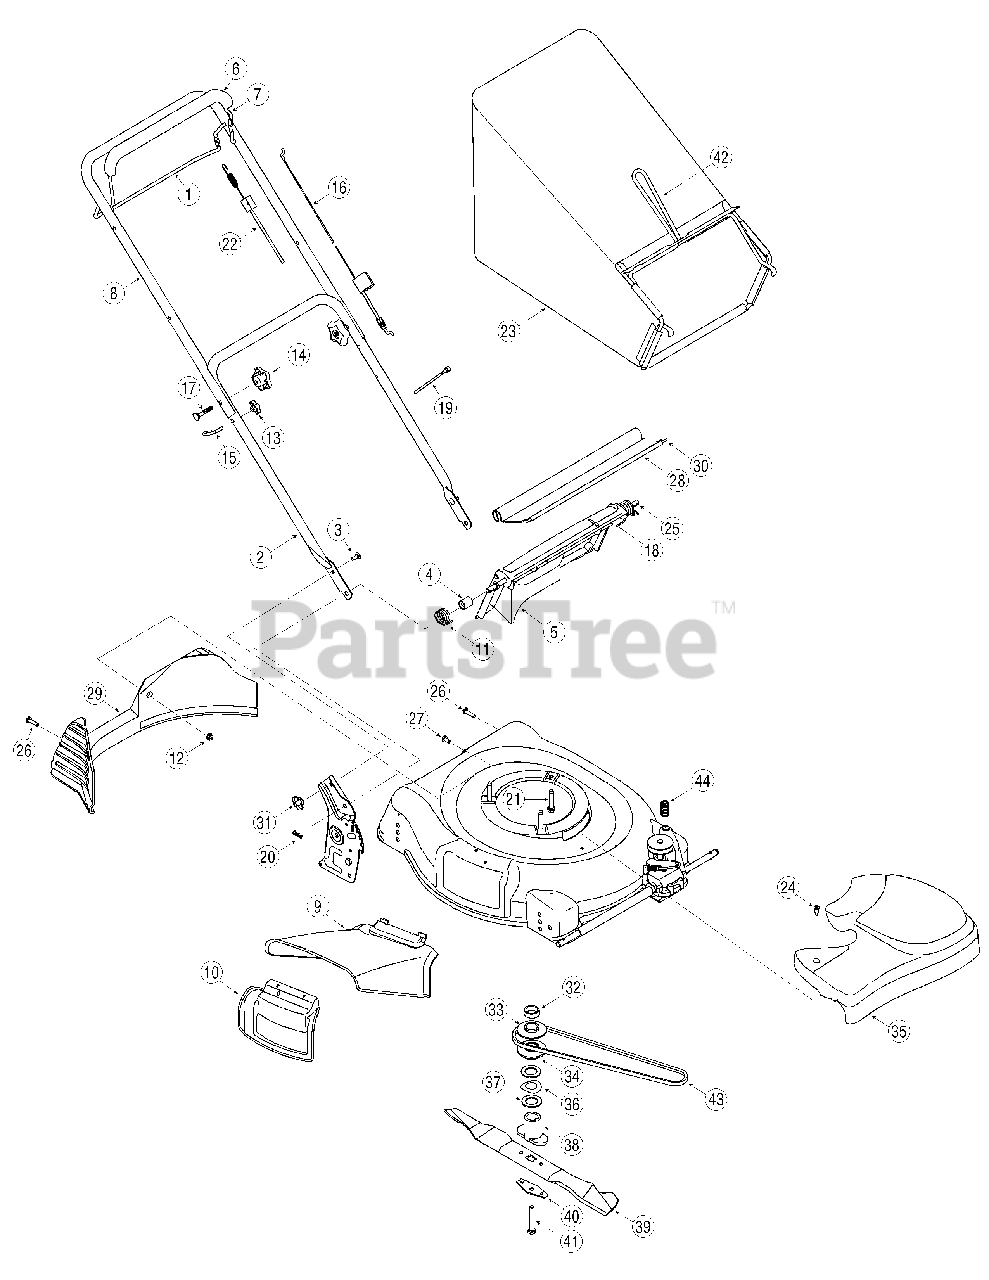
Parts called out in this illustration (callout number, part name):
1	Drive Control
3	Carriage Bolt 1/4-20
4	Spacer.375 x.50 x 1.02" Lg.
5	Rear Discharge Door
6	Deluxe Bail Cover
9	Chute Deflector
10	Mulch Plug Complete
11	Torsion Spring - RH
12	Flange Lock Nut, 1/4-20
13	Handle Knob
14	Handle Knob
15	Eye Bolt
16	Control Cable - 37.75"
17	Carriage Bolt 5/16-18 x 2.0
18	Torsion Spring - LH
19	Cable Tie
20	Cotter Pin
21	Self-Tapping Sems Screw
22	Drive Cable - 51"
23	Grassbag Assembly
24	Shoulder Screw # 12 -24
25	Pivot Rod
26	Screw, 1/4-15 x 1.25
27	Screw, 1/4-20 x .500
28	Rear Trailing Shield
29	Rear Baffle
30	Wire
31	Wing Nut
32	Sleeve Spacer
33	Upper Half Pulley
34	Key Half Pulley
35	Transmission Cover
36	Sprg Washer, 1.005 x 1.825 x .048
37	Flat Washer, 1.00 x 1.75 x .107
38	Blade Adapter w/ Star
39	21" Mulching Blade
40	Blade Bell Support
41	Hex Screw 3/8-24 x 2.50
43	V-Belt
44	Belt Tension Spring
